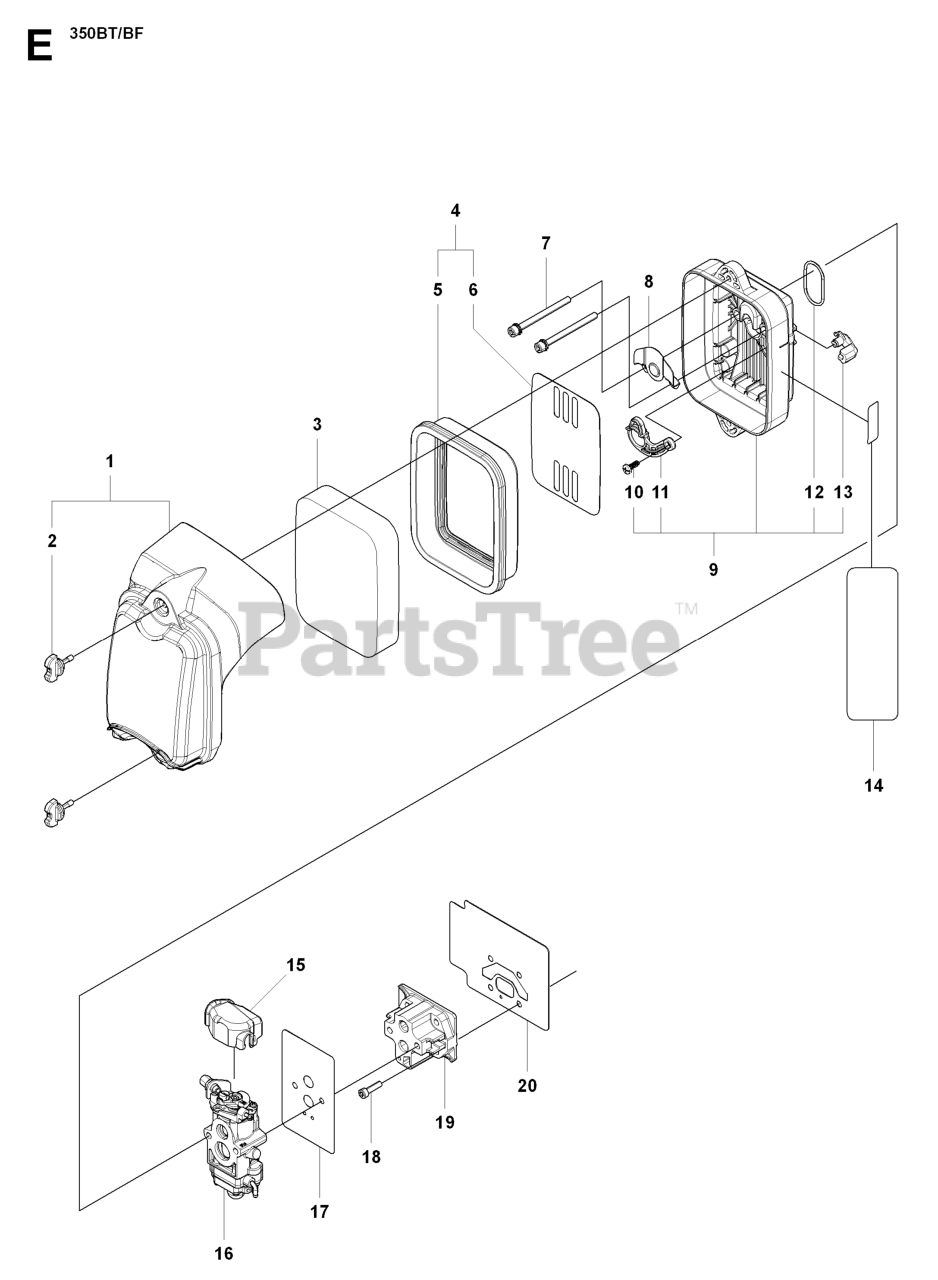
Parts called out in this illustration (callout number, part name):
3	AIR FILTER, ELEMENT
6	SCREEN
9	AIR FILTER HOLDER ASSY
16	CARBURETTOR
19	INSULATION
20	GASKET,INSULATOR
